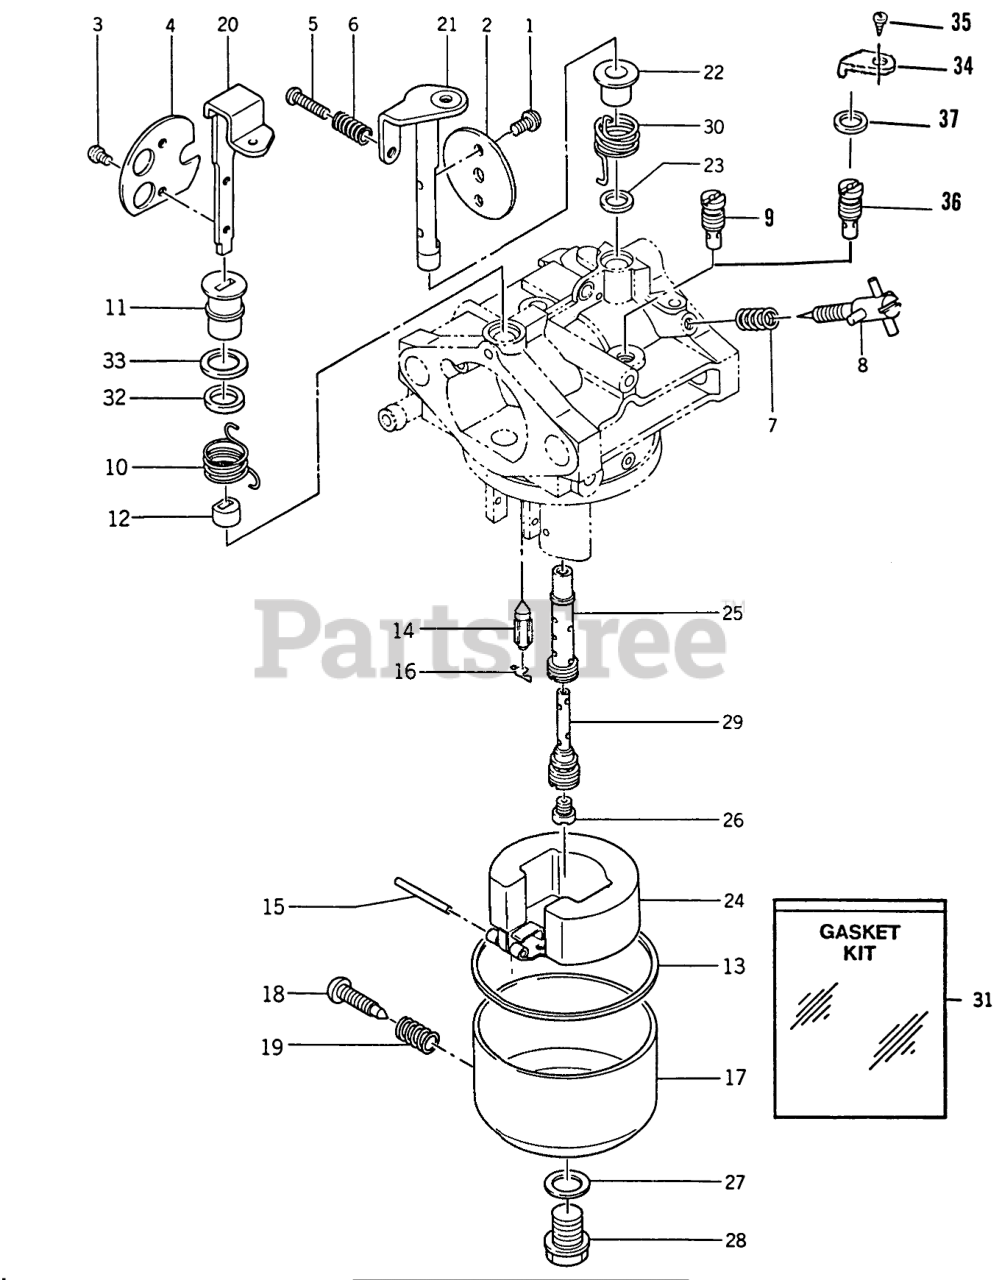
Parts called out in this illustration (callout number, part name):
1	SCREW-THROTTLE PLATE
2	VALVE THROTTLE
3	SCREW
4	VALVE CHOKE
5	SCREW
6	SPRING IDLE
7	SPRING
8	Adjuster Screw
9	Pilot Jet (#65)-Type AS/BS-13 Engine
10	SPRING
12	COLLAR
13	GASKET
14	Needle Valve Assy
15	PIN-FLOAT
17	Float Chamber Assy (includes items 18 & 19)-Type AS/BS-13 Engine.
17	Float Chamber Assy (includes items 18 & 19)-Type CS-13 Engine.
18	SCREW-DRAIN
19	SPRING
20	SHAFT-CHOKE
21	Shaft-Throttle
22	RING BUSHING
23	RING-O
24	FLOAT
25	NOZZLE-MAIN
26	JET MAIN
27	GASKET
29	HOLDER-MAIN JET
30	Spring
31	Carburetor Gasket Set
32	Washer
34	PLATE
35	Screw
36	JET-PILOT
37	O-RING
